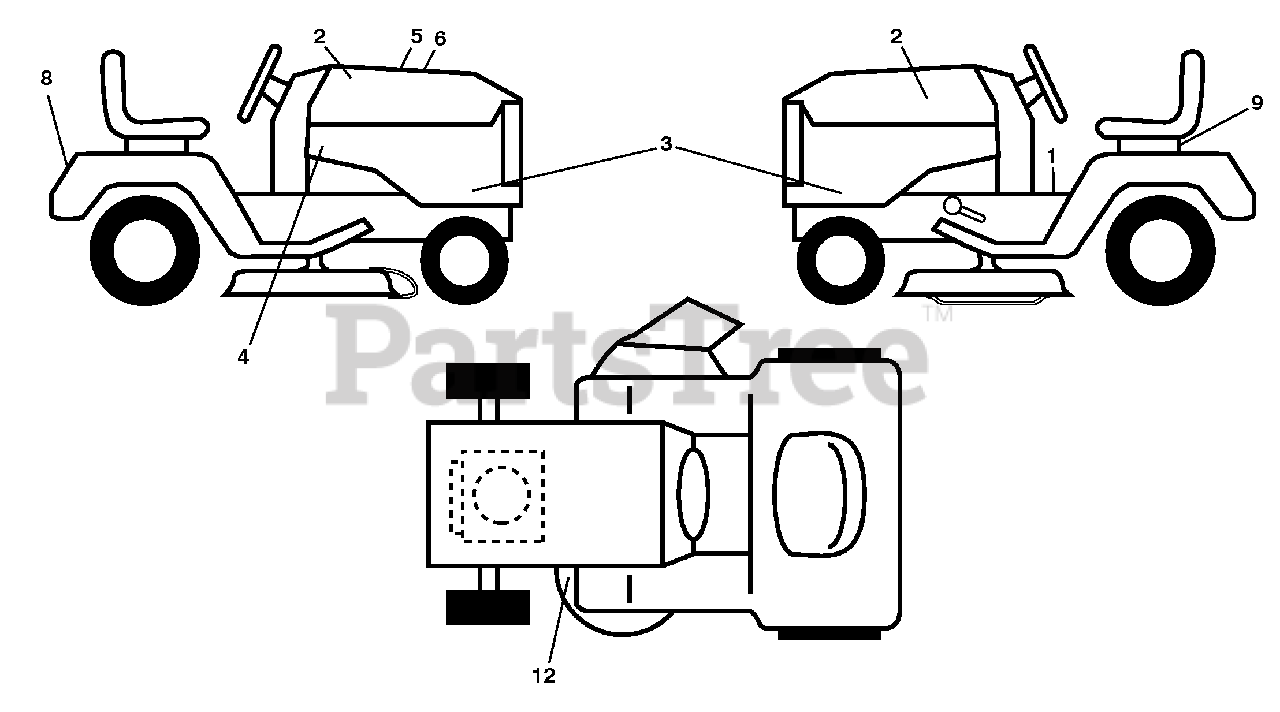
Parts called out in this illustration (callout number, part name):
1	Decal, Fender Warning
2	Decal, Hood
3	Decal, Hood Panel SD
4	Decal, Hood E85 Warning
5	Decal, Customer Respons.
6	Decal, Replacement
8	Decal, Fender
9	Decal, Battery Dnge/Poi
12	Decal, Mower V-Belt Schematic
